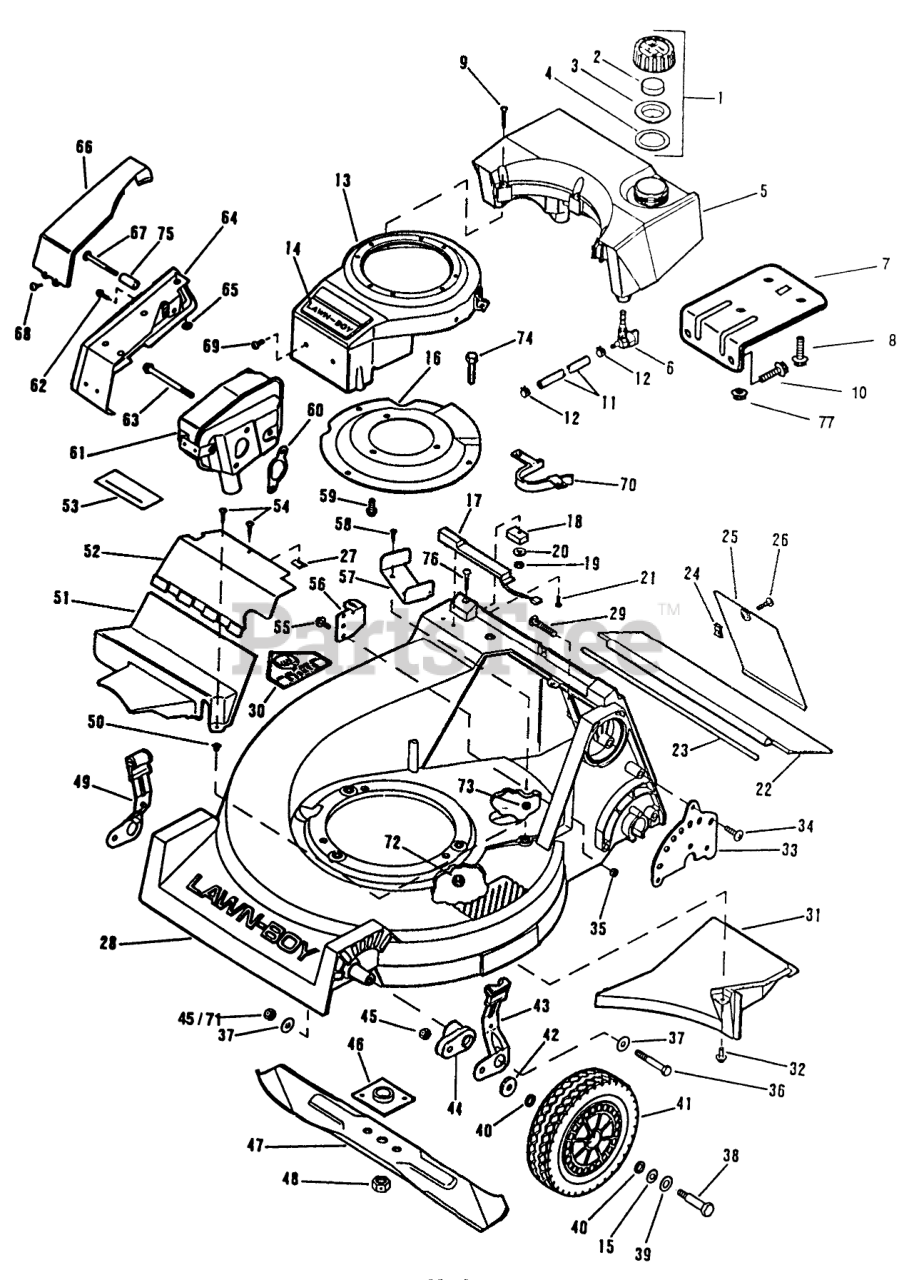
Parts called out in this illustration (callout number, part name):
1	CAP AY - F/OIL SM
2	BAFFLE - FOAM SM
3	Cover
4	GASKET-FUELCAP SM
5	Fuel Tank
6	Shut-OffValve-Fuel
7	Bracket-Fuel Tank
8	Screw
9	Screw-FuelTank
10	SCREW HEX WASH SM
11	GAS LINE SM
12	HOSE CLAMP SM
13	Shroud and Applique
14	APPLIQUE SM
15	WASHER
16	PLATE SM
17	SWITCH AY DELTA
18	MAGNET ASSY
19	NUT
20	LOCKWASHER #10
21	SCREW-STAINLESS
22	Trailing Shied
23	ROD ADVANCE
24	SPEED NUT LARSON
25	DOOR-ACCESS ELECT.
26	SCREW-CROSS RECESS
27	NUT-SPEED
28	Housing Assy
28	Housing Assembly
29	BOLT - RIBBED NECK
30	Decal
31	CHUTE BAFFLE NYL
32	Screw
33	PLATE HGT CMS
34	SCREW-BUTTON HEAD
35	LOCKNUT E
36	SCREW - HEX HEAD
37	WASHER PLAIN
38	BOLT WHEEL QUAL
39	WASHER-PLAIN
40	WASHER
41	WHEEL&TIRE 8" TRI
42	WASHER
43	KNOB & SPRING CMS
44	ARM HGT ADJ BLACK
45	NUT-JAM, LOCKING
46	PLATE AND COLLAR ASM
47	21" Blade
48	NUT-BLADE
49	KNOB & SPRING CMS
50	NUT-CLIP
51	COVER-DRIVE-LOWER
52	COVER-UPPER
53	DECAL
54	SCREW S
55	Screw
56	ANCHOR-CABLE
57	BELT GUIDELB
58	SCREW TH FORM TEB
59	SCREW SM
60	GASKET - EXH SM
61	Muffler
62	SCREW S
63	SCREW-SEMS
64	MUFFLER GUARD AY
65	NUT-PUSH
66	COVER MUFFLER CP
67	SCREW SM
68	SCREW SM
69	SCREW SM
70	GUIDE-BELT SM
71	NUT
72	NUT-LOCK F
73	NUT C/LOCK E
74	SCREW-HH
75	SPACER S
76	SCREW
76	SCREW S
77	NUT SM
